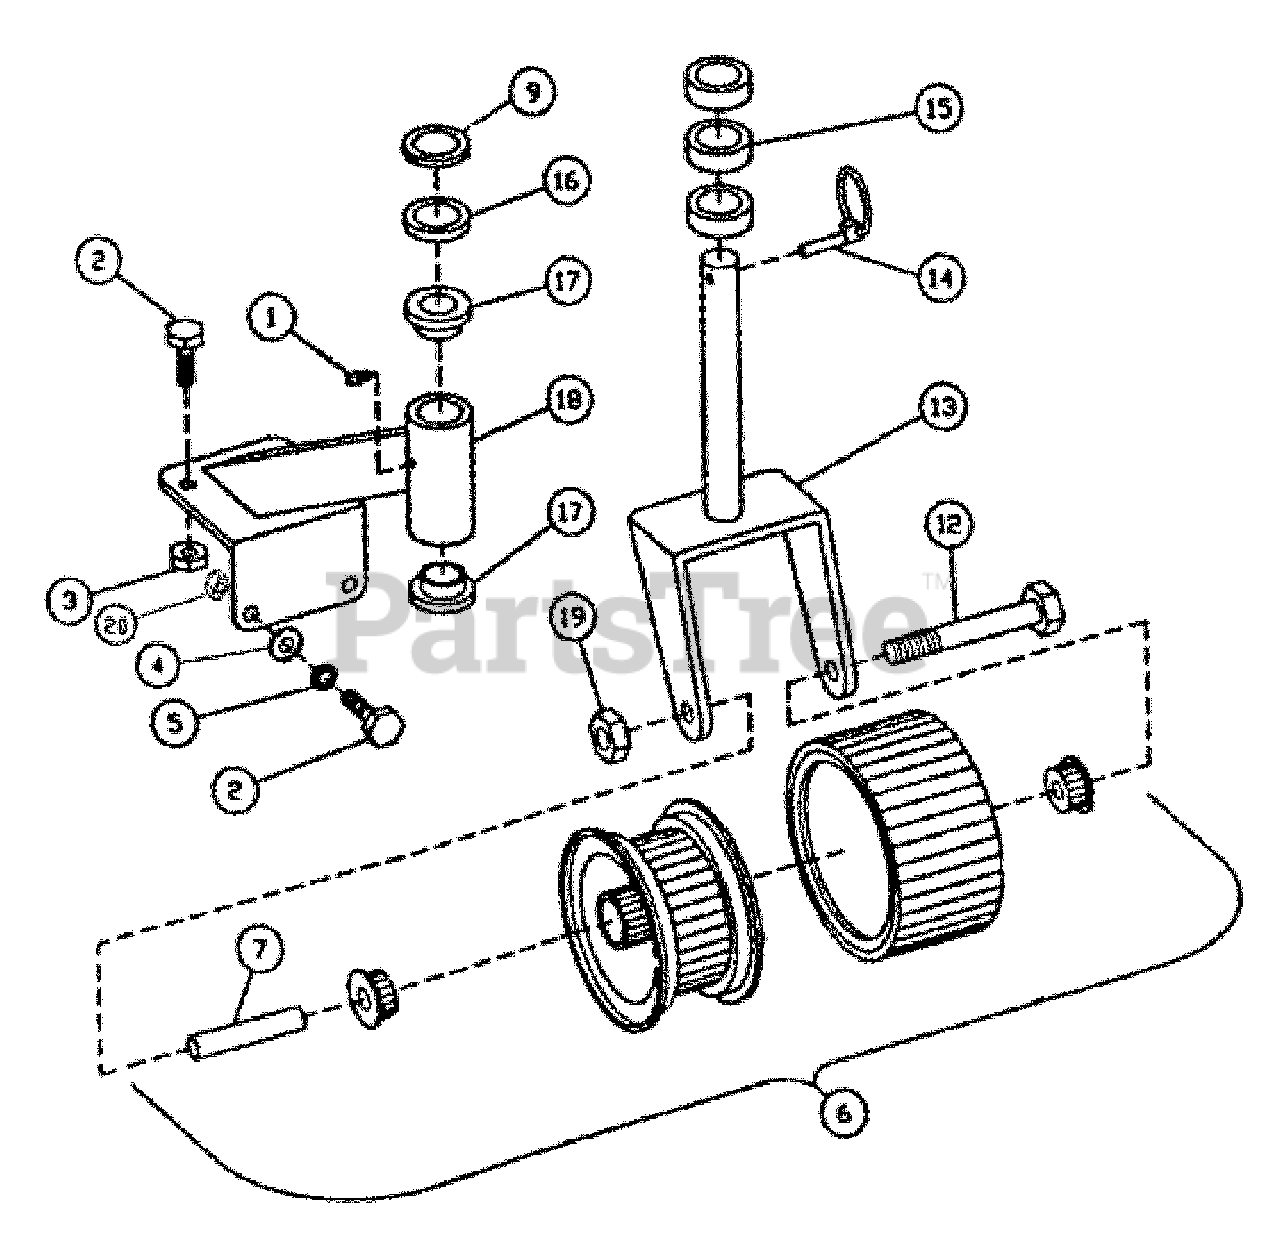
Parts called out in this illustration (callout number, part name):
1	GREASE FTG (10 PACK) 200-026
2	M10X1.5X25MM HHB GR8.8
3	200-006 NYLON NUT M10
4	WASHER, 3/8 STD FLAT
5	3/8HELICAL L-WASHER
6	100-092 CASTOR WHEEL ASM
7	100-093 PIVOT TUBE CASTO
9	100-015 WASHER 2`26ID
12	200-057 HEX BOLT M12`140
13	100-096 CASTOR YOKE
14	100-097 LYNCH PIN
15	100-098 SPACER 13
16	100-099 SPACER 6.5
17	100-100 BUSHING CASTOR
18	100-101 CASTOR SUPPORT
19	200-007 NYLON NUT M12
